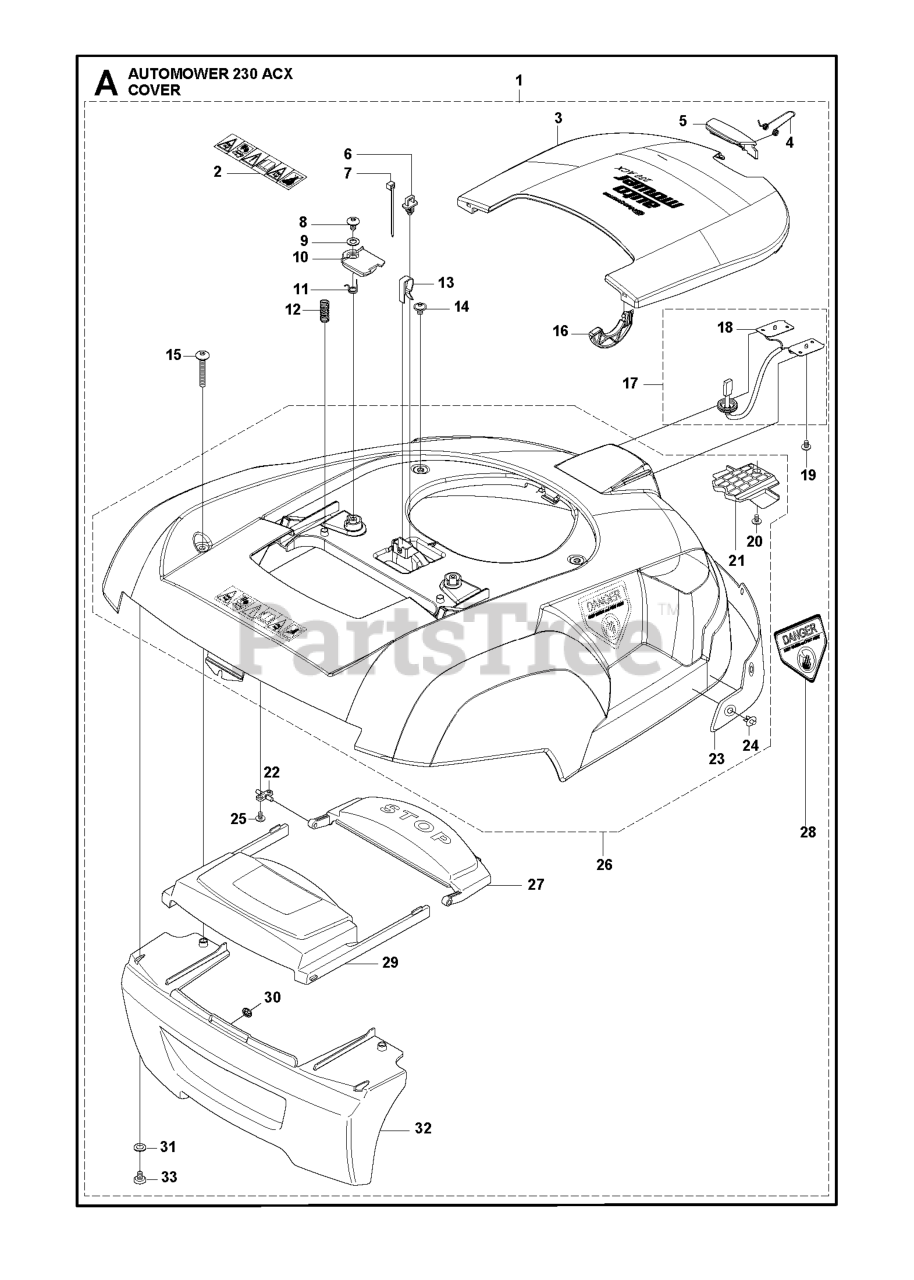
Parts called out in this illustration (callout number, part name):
2	LABEL WARNING
3	COVER 230 ACX
5	HEIGHT ADJ. COVER LATCH
6	BRACKET FOR BAND
8	SCREW SILVER 10MM
13	CLIP RETAINER
15	SCREW IHPANM
17	CABLE ASSY
18	THIN PLATE
19	SCREW WHITE 6MM
20	SCREW 12MM
25	SCREW SILVER 10MM
26	MAIN BODY KIT 230 ACX
28	LABEL, DANGER
32	BUMPER, COVER
33	SCREW 14MM
